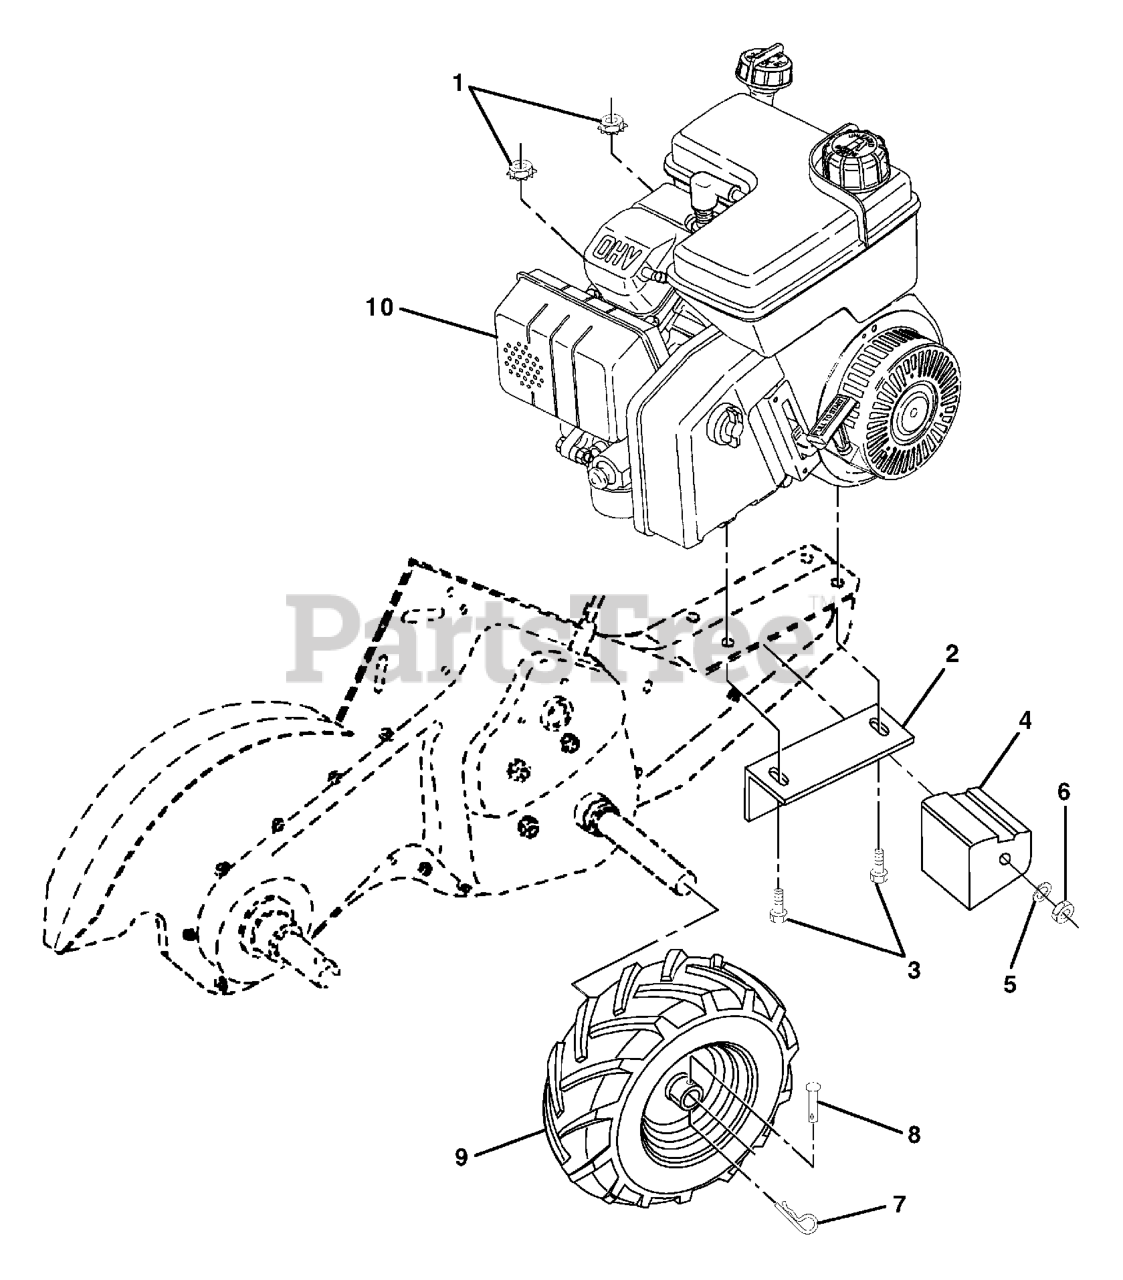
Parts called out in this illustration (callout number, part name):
1	NUT
2	DNO BRACKET RH CRT
3	BOLT
4	COUNTERWEIGHT, RH
5	WASHER, LOCK 3/8
6	NUT.HEX.3/8-16UNC
7	RETAINER M
8	RIVET,DRILLED
9	TIRE.16X4-8.CHEVRON.TILLER
9	RIM
9	VALVE STEM LT
10	Engine
